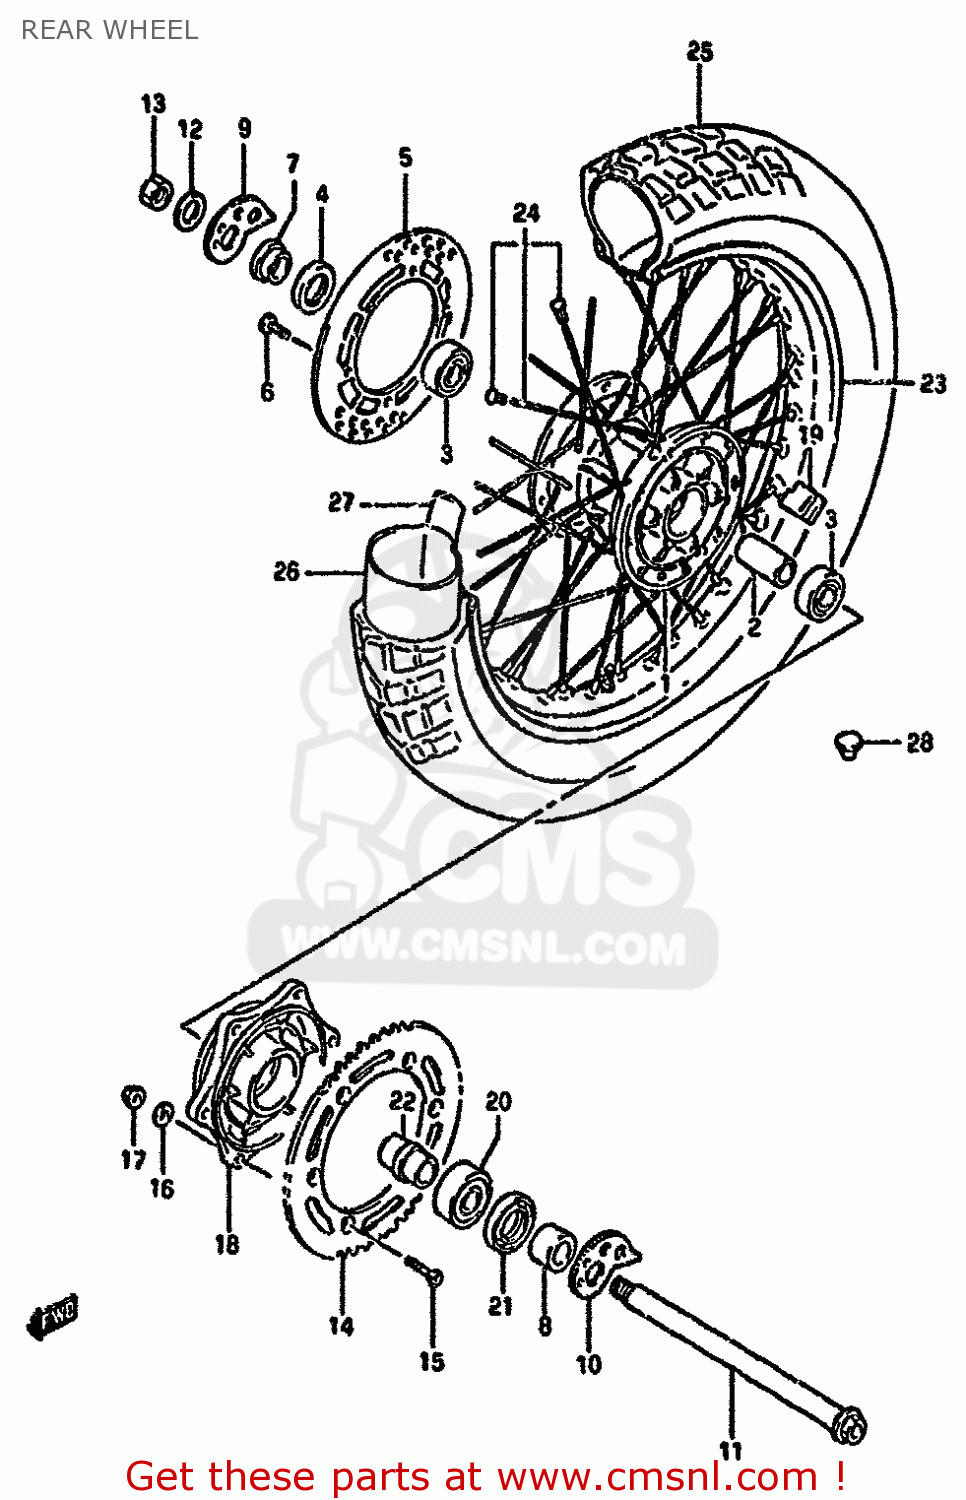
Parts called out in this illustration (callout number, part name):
1	HUB,RR WHEEL
2	SPACER,RR HUB BEARING
3	BEARING
4	SEAL,OIL(26X47X5)
5	DISC,RR BRAKE
6	BOLT
7	SPACER,RR AXLE,R
8	SPACER,RR AXLE,L
9	ADJUSTER,CHAIN
10	ADJUSTER,CHAIN,L
11	AXLE,RR
12	WASHER(19X32X3.2)
13	NUT 18MM
14	SPROCKET,REAR
15	BOLT(8X30.5)
16	WASHER
17	NUT
18	DRUM,REAR SPROCKET MOUNT
19	ABSORBER,RR HUB SHOCK
20	BEARING(25X52X15)
21	SEAL,OIL(34X52X6)
22	RETAINER,RR SPROCKET DRUM
23	RIM,REAR WHEEL (18X2.15)
24	SPOKE SET,RR WHEEL
25	TIRE
26	TUBE ASSEMBLY,WHEEL,INNER
27	PROTECTOR,WHL INR TUBE
28	CAP(OD:12)
